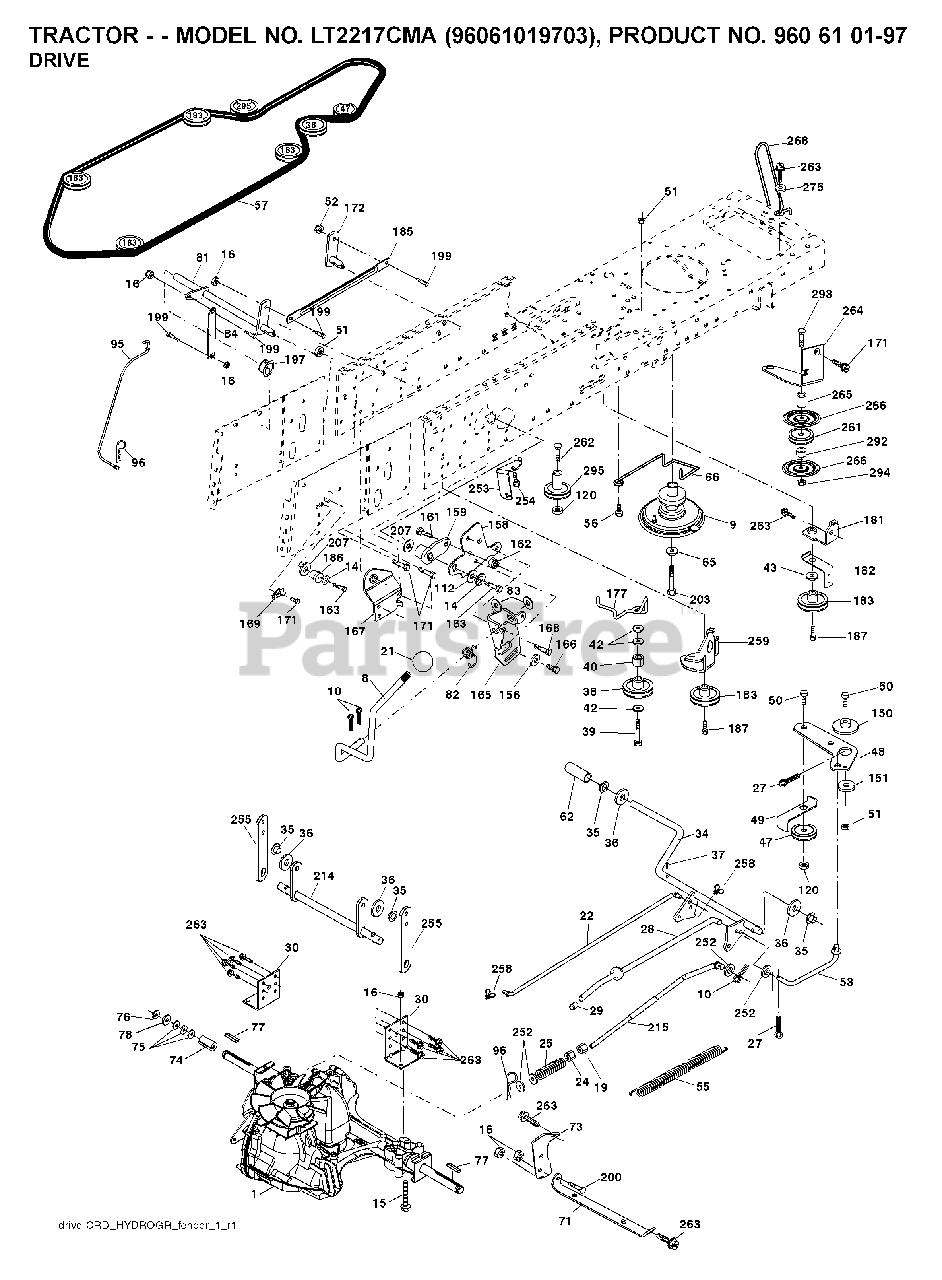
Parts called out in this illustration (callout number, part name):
8	ROD SHIFT FENDER ADJUST LT
10	PIN COTTER
14	LOCKWASHER
15	BOLT HEX 5/16-18 GR 5
16	NUT.71038.31-18.HEX.NYLOCK
19	NUT
21	PISTOL KNOB
24	NUT
27	COTTER PIN
28	ROD, PARKING BRAKE
29	PLUNGER CAP
30	BRKT, TRNSXLE MNT 20"
34	SHAFT, FOOT PEDAL
35	BEARING.NYLON
36	WASHER LT
37	DRIVE PIN
38	PULLEY.FLAT
42	WASHER
47	IDLER PULLEY
48	BELLCRANK, CLUTCH
49	RETAIN BELT
50	BOLT.3/8-16X1.50
51	LOCKNUT
52	LOCKNUT
53	LINK.CLUTCH.7.66.2005
55	SPRING, RETURN LT
56	SCREW.3/8-16
62	PEDAL COVER T
65	LOCKWASHER
66	KEEPER BELT ENGINE
71	STRAP TORQUE LH HYDRO
73	STRAP TORQUE RH HYDRO
74	SPACER AXLE
76	E-RING LT
77	SQUARE KEY
81	SHAFT ASSY
82	SHIFT SPRING
83	WASHER
96	RETAINER M
112	WASHER LT
120	NUT LOCK FLG 3/8-16 UNC
150	BUSHING.BELLCRANK.GRD.DR
151	WASHER 12/32X2X10GA
156	WASHER.SRRTD.5/16
158	BRACKET
159	HUB.SHIFT
161	BOLT
162	NUT.CROWNLOCK.1/4
165	RP BRACKET
167	BRACKET
168	BOLT.SHOULDER.5/16-18X
169	PLATE.FASTENING.CROSS.SHAFT
187	BOLT.5/16-18X1.25
197	NYLINER SNAP 5/8" ID
199	BOLT SHOULDER 5/16-18 UNC
200	BOLT
207	WASHER NYL
254	SCREW 3/8-16X1
258	CLIP RETAINER
261	FLAT IDLER PULLEY
263	SCREW, 3/8-16X3/4
275	WASHER
294	NUT, HEX 3/8-16
295	PULLEY IDLER COMPOSITE
